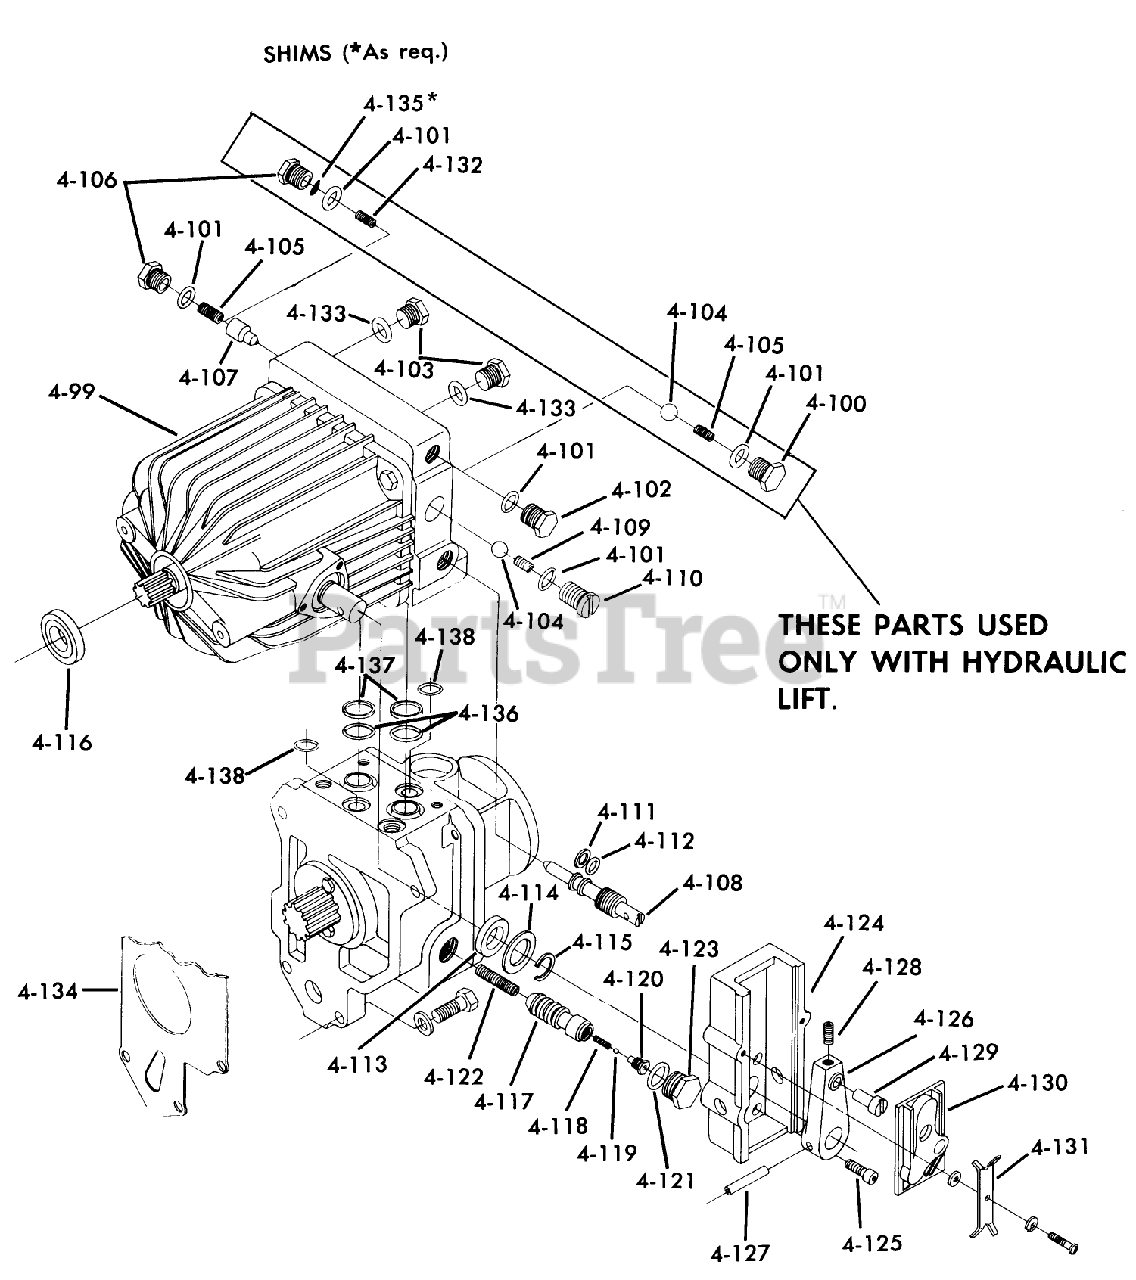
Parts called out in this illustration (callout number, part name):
4-99	Hydro Unit
4-100	Plug
4-101	O RING
4-103	Plug-Hex 9/16-18
4-105	Spring Chg. Rel. Valve
4-107	Cone
4-108	VALVE
4-109	Spring
4-110	PLUG
4-111	O-RING
4-112	Back Up Ring
4-113	SEAL
4-114	WASHER-LAMBERT
4-115	RING-LAMBERT
4-116	SEAL
4-117	Sleeve
4-118	SPRING
4-120	Valve
4-121	O-Ring
4-122	Spring
4-124	SUPPORT CAM BLOCK
4-125	SHCS 1/4-20 X 1/2
4-126	Belt Guide
4-127	PIN-ROLL 1/4 X 1 1/4
4-129	ECC CAM FOLLOWER
4-130	CAM
4-131	TENSION PLATE
4-131	SCREW
4-131	LOCKWASHER
4-131	WASHER
4-132	SPRING VALVE SUNSTR
4-133	0-Ring
4-134	GASKET
4-135	Shim Set
4-136	O RING
4-137	RING BACKUP
4-138	O RING
